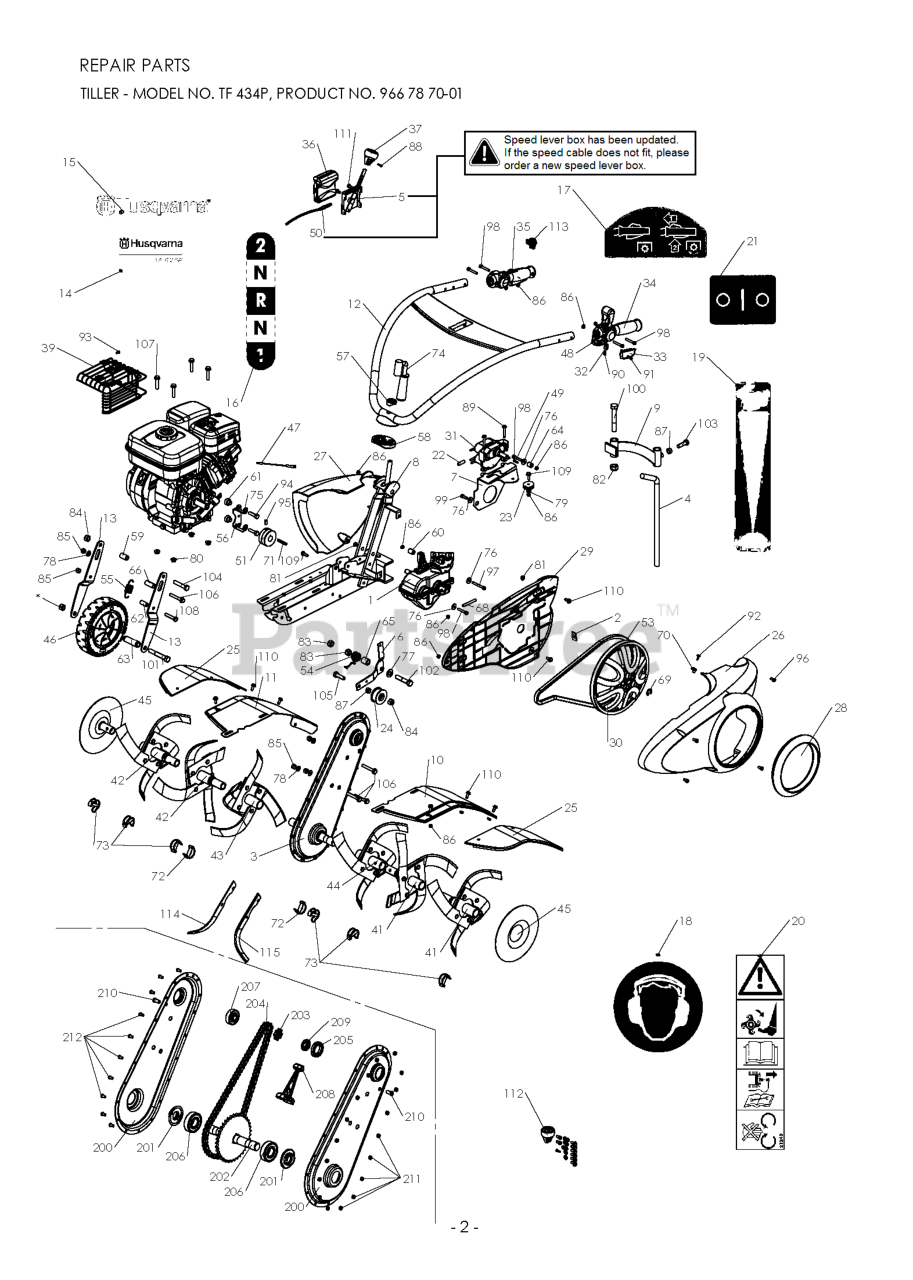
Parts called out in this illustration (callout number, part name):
48	THROTTLE CABLE THROTTLE CABLE
69	RETAINER RING
86	Blocking nut M 6 Z
205	BALL BEARING
211	Blocking nut M 6 Z
